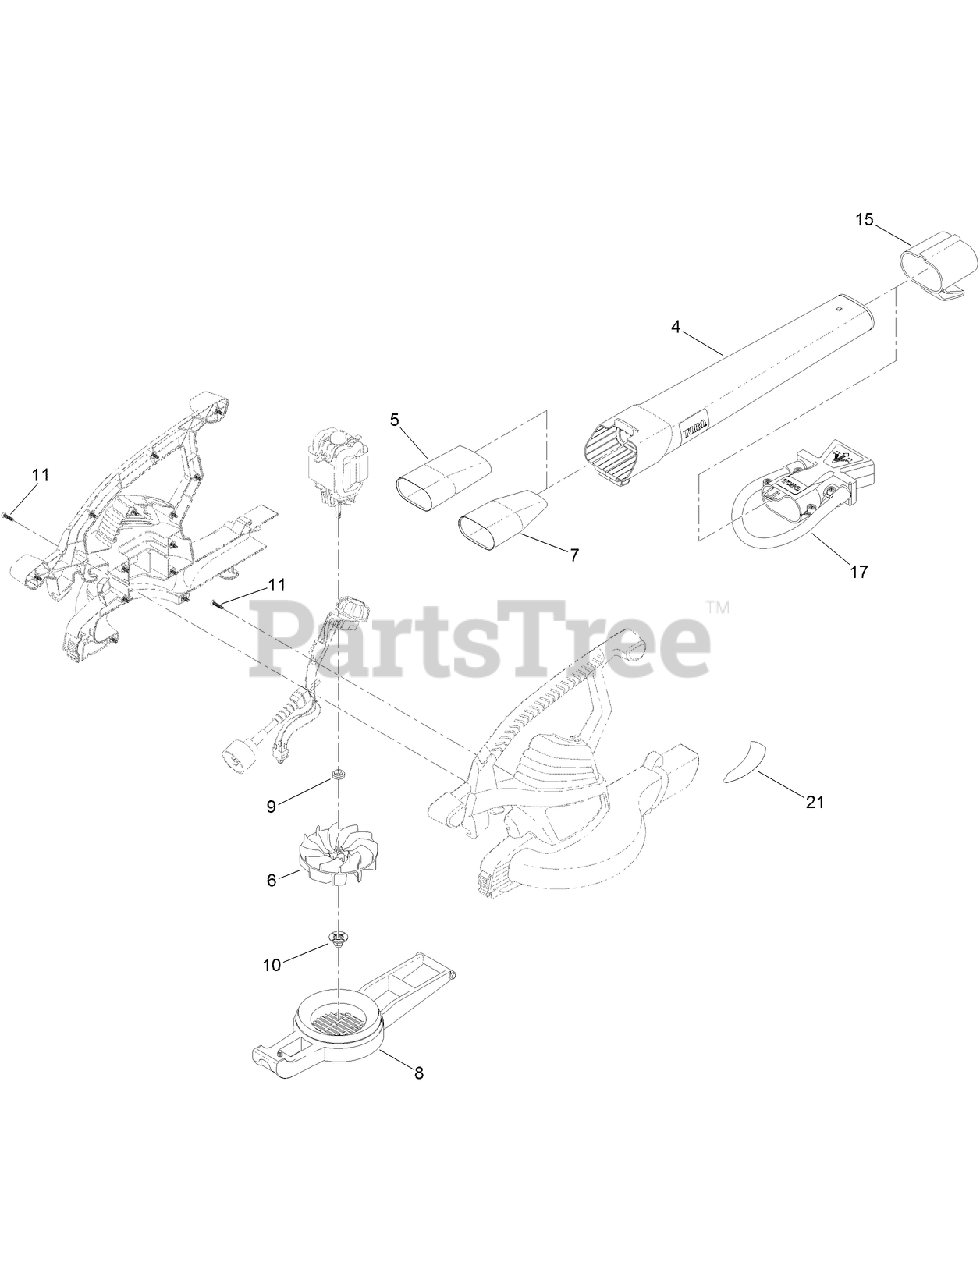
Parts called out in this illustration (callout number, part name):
4	TUBE-BLOWER
5	TUBE-INSERT
6	IMPELLER ASM
7	INSERT-TUBE, MPH
8	COVER-INLET
9	BUSHING-MOTOR
10	NUT-IMPELLER
11	SCREW-PPH
15	ADAPTER-WRAP, CORD
17	OSCILLATOR NOZZLE ASM
21	DECAL-SHREDDING
